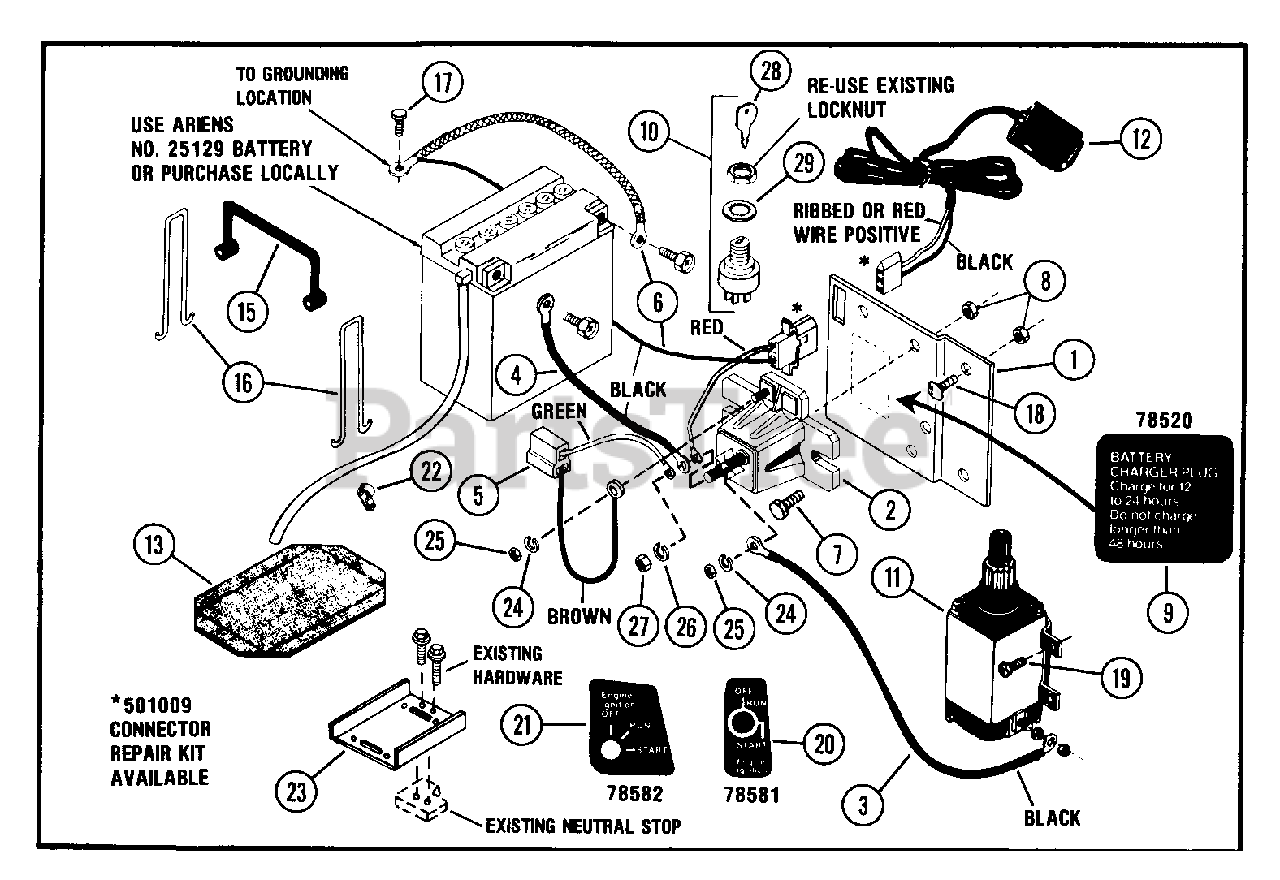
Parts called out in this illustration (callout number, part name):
1	BRACKET SOLENOID
2	SOLENOID
3	GROUND CABLE
4	GROUND CABLE
5	WIRING HARNESS SWITCH
6	WIRING HARNESS BATTERY CHARGER
7	BLT-HEX .25-20X.50 PL GR2
8	NUT-LK-CTR .250-20 PL
9	CHARGING DECAL
10	IGNITION SWITCH ASSEMBLY
12	BATTERY CHARGER
13	RUBBER PAD
15	BATTERY STRAP
16	HOOK
17	SCR-TAP 10-24X.375 CRPH 1A
18	BLT-RDHDSQNK .25-20X.62 PL
19	SCR-CAP CR SEMS .25-20X.50 PL
20	ELECTRIC START DECAL
21	ENGINE IGNITION DECAL
23	BATTERY TRAY
24	WSHR-LK .312X.097 PL HVY
25	NUT-JAM .312-24 PL
26	WSHR-LK 10X.047 MED PL
27	NUT 10-32 PL
28	KEYS
29	WSHR-LK-INT .625X.045 PL
